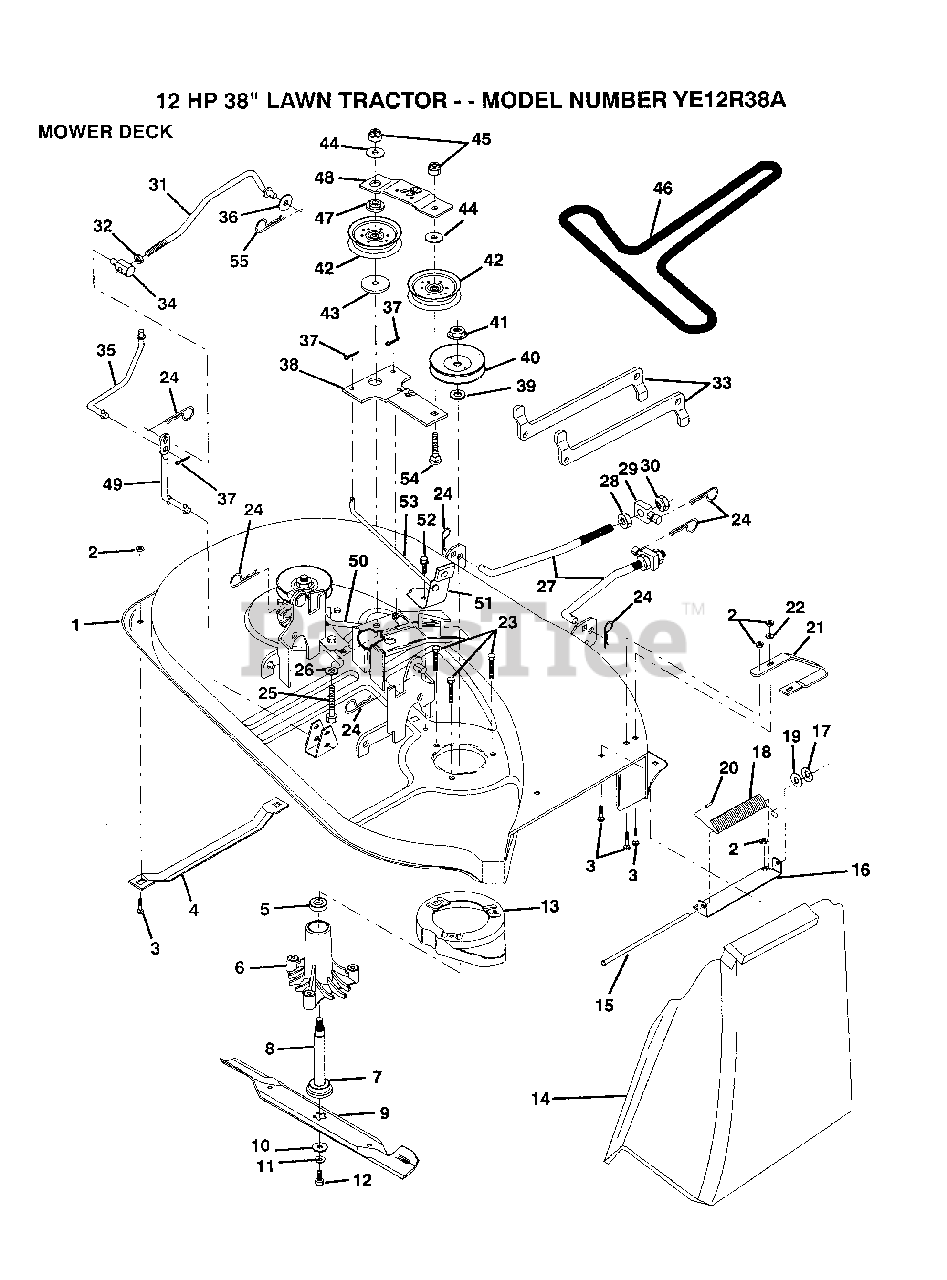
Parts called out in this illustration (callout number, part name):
1	MOWER DECK ASSY
3	BOLT
4	RUNNER-LH M
5	BEARING
6	HSG ASM MANDREL
7	BEARING.BALL
10	WASHER BLADE
12	BLADE BOLT
14	DEFLECTOR-SHLD T
15	ROD-HINGE T
17	NUT PUSH M
19	WASHER
20	CAP-SLEEVE LT
21	RUNNER RH
22	WASHER M
25	BOLT
26	WASHER GT
27	SEAL.COVER.BAGGER
28	NUT
29	TRUNION
30	NUT.LK.W/WSH.1/2.
31	CLUTCH ROD PRI
32	NUT
33	SUSP ARM REAR
34	TRUNNION
35	CLUTCH ROD SEC
36	WASHER
38	IDLER ARM ASSY
39	WASHER
42	FLAT IDLER PULLEY
43	SPACER RETAINER
44	WASHER GT
46	BELT-V.88.12.MW
47	RETAINER SPACER
48	IDLER ARM STIFF
49	PIVOT ROD
50	BRAKE ROD LH
51	BRAKE ASM
52	SCREW
53	BRAKE ROD RH
54	BOLT
55	SPRING.RETAINER
